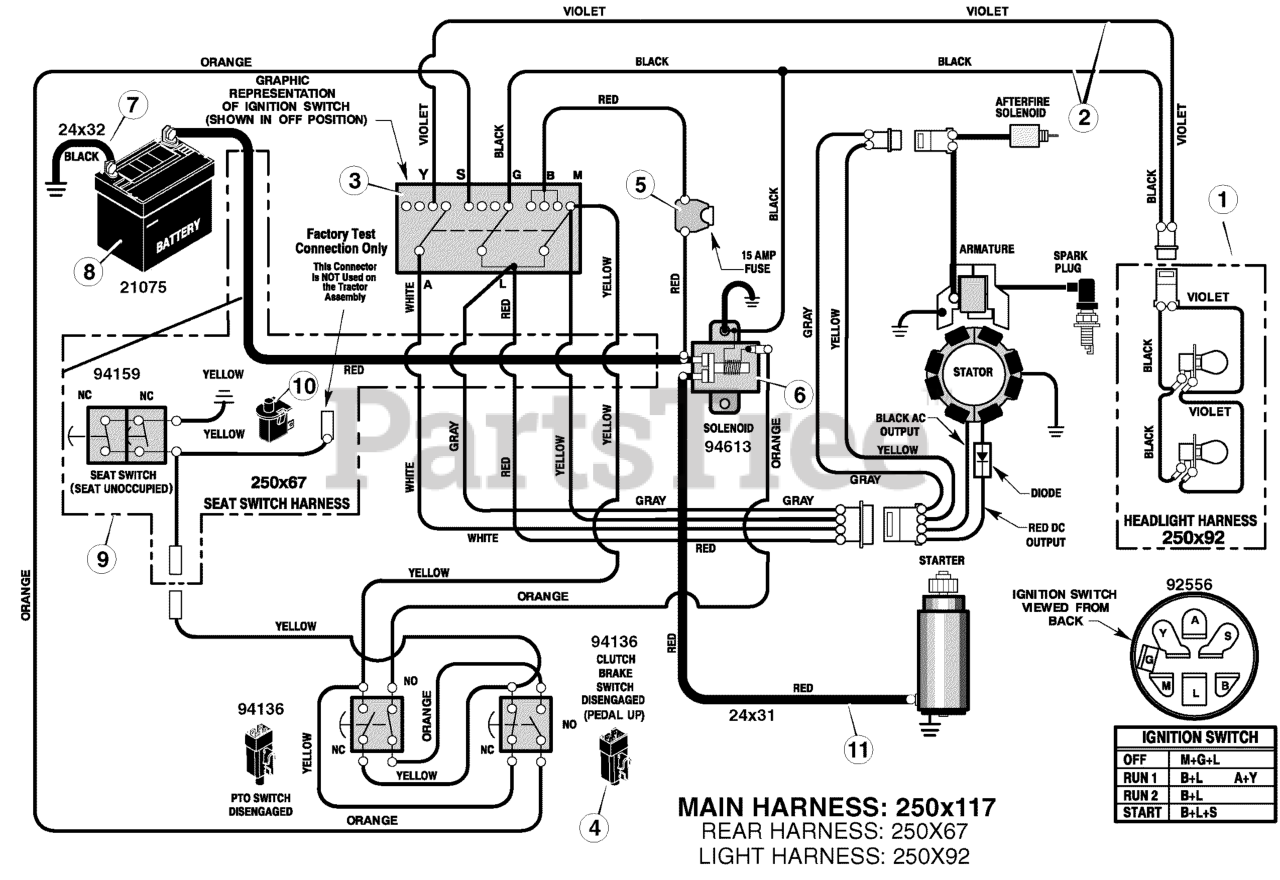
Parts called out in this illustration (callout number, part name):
1	Harness, Light Wire
1	Socket, Light
1	Bulb, Light
2	Harness, Chassis Wire
3	Switch, Ignition
3	Key, Ignition
3	Nut, Hex
3	Cap, Ignition
4	Switch, Limit
5	Fuse
5	Holder, Fuse
6	Solenoid
6	Screw, Mounting
6	Locknut
7	Cable, Battery Ground
7	Screw, Ground Cable
8	Battery
8	Bolt, Carriage
8	Wingnut
9	Harness, Seat Switch Wire
10	Switch, Seat Sensor
11	Cable
